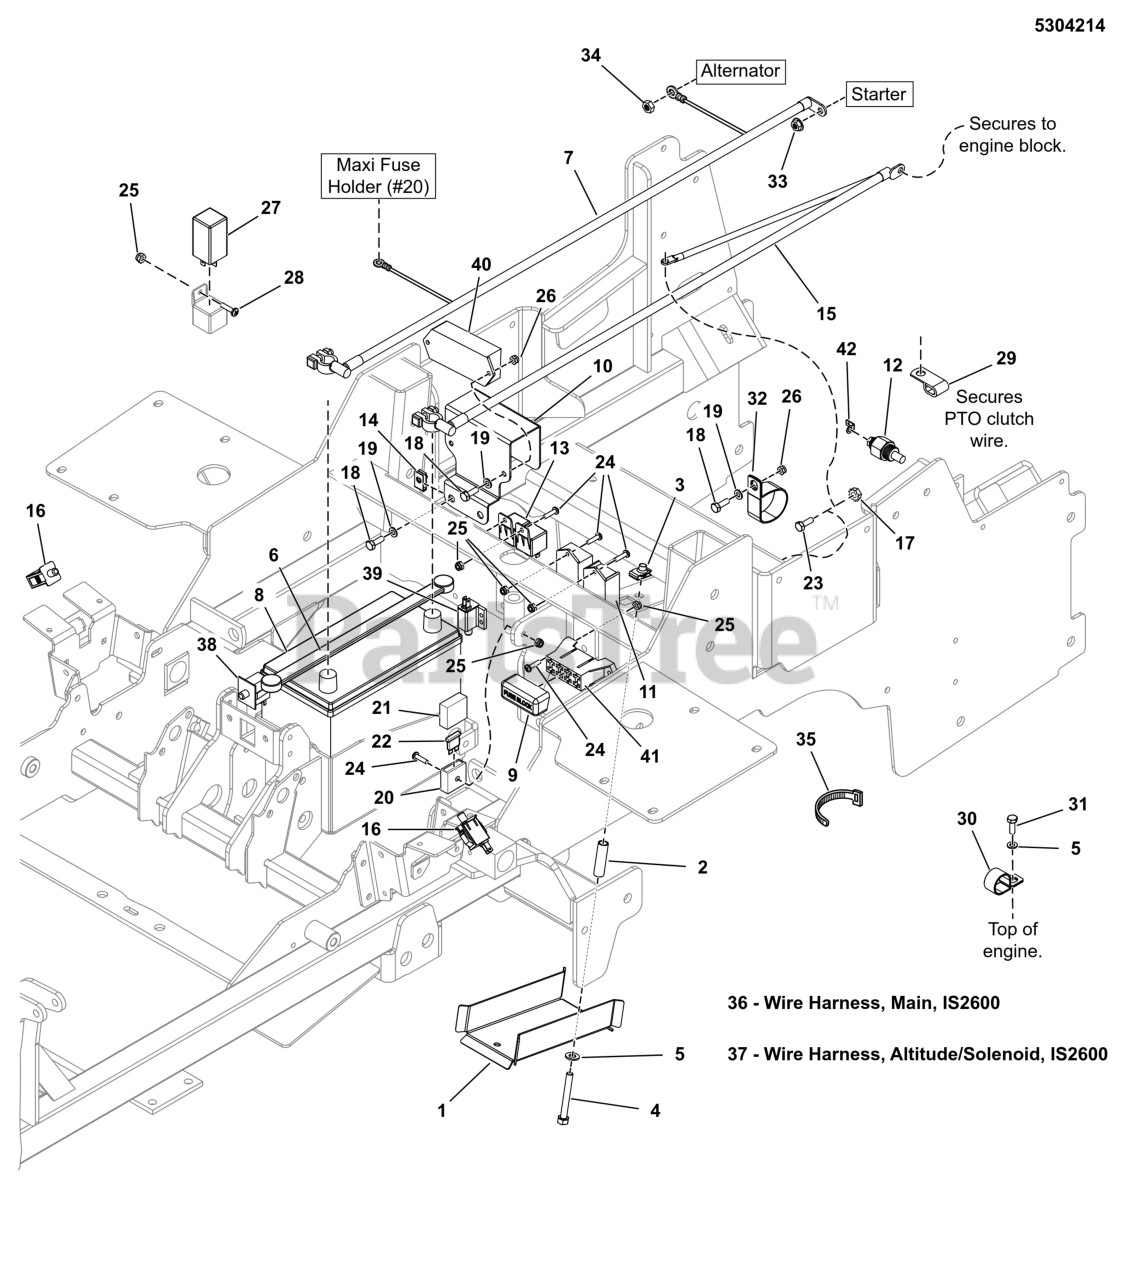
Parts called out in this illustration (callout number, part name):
1	CHANNEL, HOSE & WIRE - BLK
2	SPACER, .38 X .50 X 1.78 YZ
3	BODY CLIP, 5/16-18-7GA MATERIAL
4	BOLT, 5/16-18 X 2-1/2" GD5 YZ
5	WASHER, 5/16" SAE
6	STRAP, BATTERY, 14 LONG, Rubber
7	ASSEMBLY, POS BATTERY CABLE, IS2600
9	COVER, VINYL, FUSE BLOCK
10	MOUNT, DRIVER MODULE - RED
11	MODULE, TIME DELAY
12	SENDER, WATER TEMPERATURE
13	RELAY, 12 VOLT, 50 AMP, N.O.
14	BODY CLIP, 1/4-20 X 1/2" DEEP
15	BATTERY CABLE, NEG
16	SWITCH, PLUNGER, NO, SINGLE POLE, SNAP-IN
17	NUT-HEX KEPS 5/16-18 CL/ZC
18	BOLT, 1/4"-20 X 3/4" GD5 YZ
19	WASHER, 1/4 SAE
20	FUSE HOLDER, MAXI
21	COVER, FUSE HOLDER, MAXI
22	FUSE, MAXI, 40A
23	BOLT, 5/16-18 X 1" , SELF-TAPPING
24	SCREW, #10-24 X 3/4" ROUND PHILLIPS
25	NUT, Hex, Nylon Lock, #10-24
26	NUT, 1/4-20 Hex Nylock Flange
27	MODULE, PRE-HEAT, 4 SECONDS
28	SCREW, #10-24 X 1/2" ROUND PHILLIPS
29	CLAMP, 5/16", DOUBLE, WIRE & TUBE
30	CLAMP, TUBE & WIRING, 1.062 ID
31	BOLT, M8-1.25 X 16MM GD8.8
32	CLAMP, VINYL INSULATED, 1.75
33	NUT, M8-1.25 Hex Serrated Flange
34	NUT, M6-1.0
35	TIE, SELF-LOCKING, 12"
36	WIRE HARNESS, MAIN, IS2600
37	WIRE HARNESS, ALTITUDE/SOLENOID, IS2600
38	SWITCH, PLUNGER, NO/NC SNAP-IN, LOW PROFILE
39	SWITCH, PLUNGER, N.C.
40	ALTITUDE MODULE (SEE YANMAR ENGINE PARTS DEALER)
41	FUSE, BLOCK (SV)
42	TERM #10 X .250 SPADE (90 DEG)
